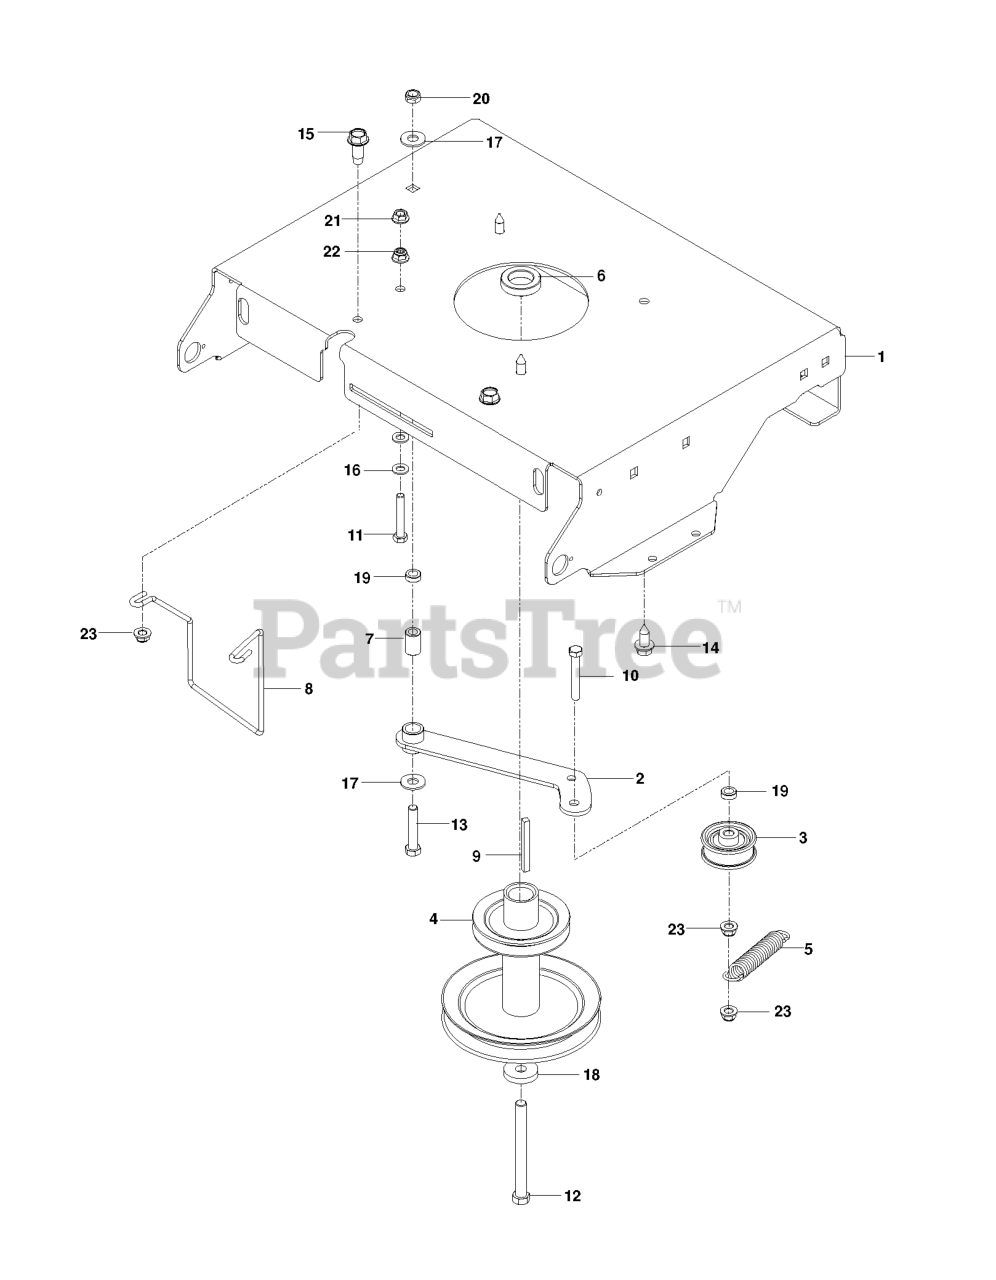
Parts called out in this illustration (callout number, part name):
1	PLATE.ENGINE.ORG
2	!DLER ARM WLDMNT, BLACK
3	PULLEY IDLER
4	PULLEY, ENGINE 6.5
5	SPRING - 3.50
8	KEEPER.BELT.ENGINE.42.SZ
9	KEY 1/4 SQ X 2-1/2
10	TAPBOLT, 3/8C X 3
11	HCS 5/16-18X2
12	HCS 7/16-20 X 4 GR5 ZD
13	HCS 3/8C X 2
14	HHFS 3/8-16 X 1.0 THD FORMING
15	BOLT 3/8-16 X 1.0
16	FLAT WASHER 5/16 SAE
17	WASHER 3/8 FLAT
18	WASHER .43X1.38X.25
19	WASHER 3/8 X 3/4 X .187 TK
20	NUT HEX 3/8-16 NYLON, THIN
21	NUT 5/16C WHIZ
22	5/16-18 NYLOC FLANGE NUT
23	NUT 3/8-16 HEX FLG NYLOC ZD
